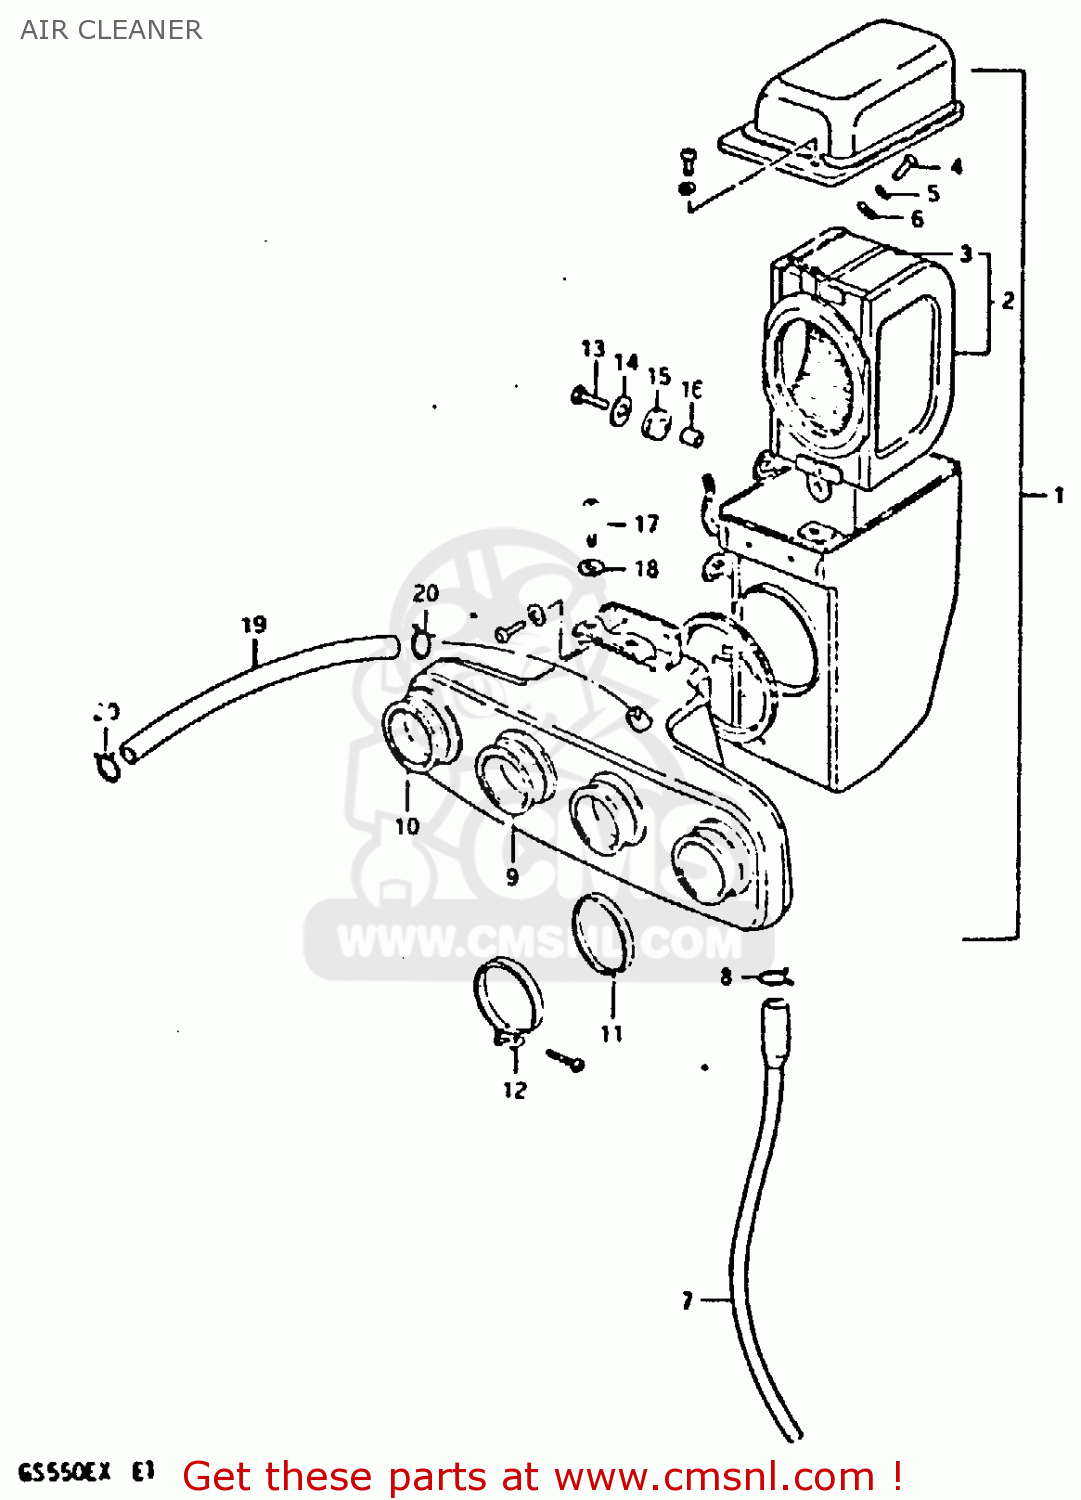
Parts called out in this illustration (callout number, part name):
1	CLEANER ASSEMBLY,AIR
2	FILTER ASSY
3	FILTER
4	SCREW
5	LOCK WASHER
6	WASHER
7	DRAIN TUBE
8	CLIP
9	TUBE,AIR CLEANER OUTLET A
10	TUBE,AIR CLEANER OUTLET B
11	RING,CARBURETOR AIR INLET HOSE
12	CLAMP
13	BOLT
14	WASHER
15	CUSHION
16	SPACER (6.1X9X9)
17	SCREW 6X12
18	WASHER
19	HOSE
20	CLIP
